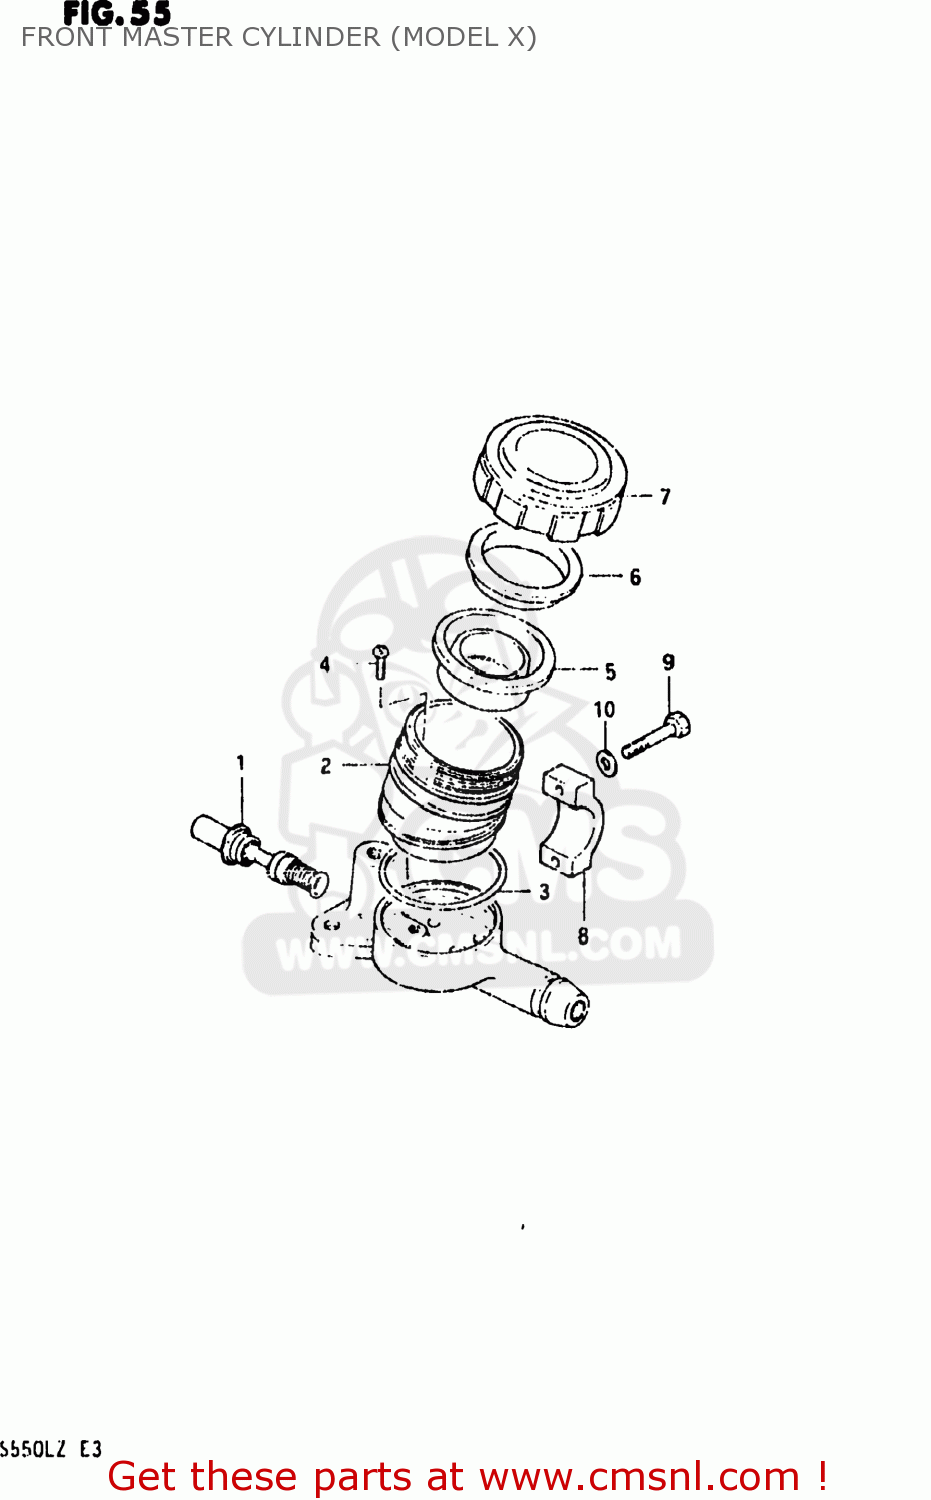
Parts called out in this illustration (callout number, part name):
1	PISTON & CUP SET
2	RESERVOIR
3	O RING
4	SCREW,MASTER CYLINDER
5	DIAPHRAGM
6	PLATE
7	CAP,MASTER CYLINDER,REAR
8	HOLDER,MASTER CYLINDER
9	BOLT
10	WASHER
